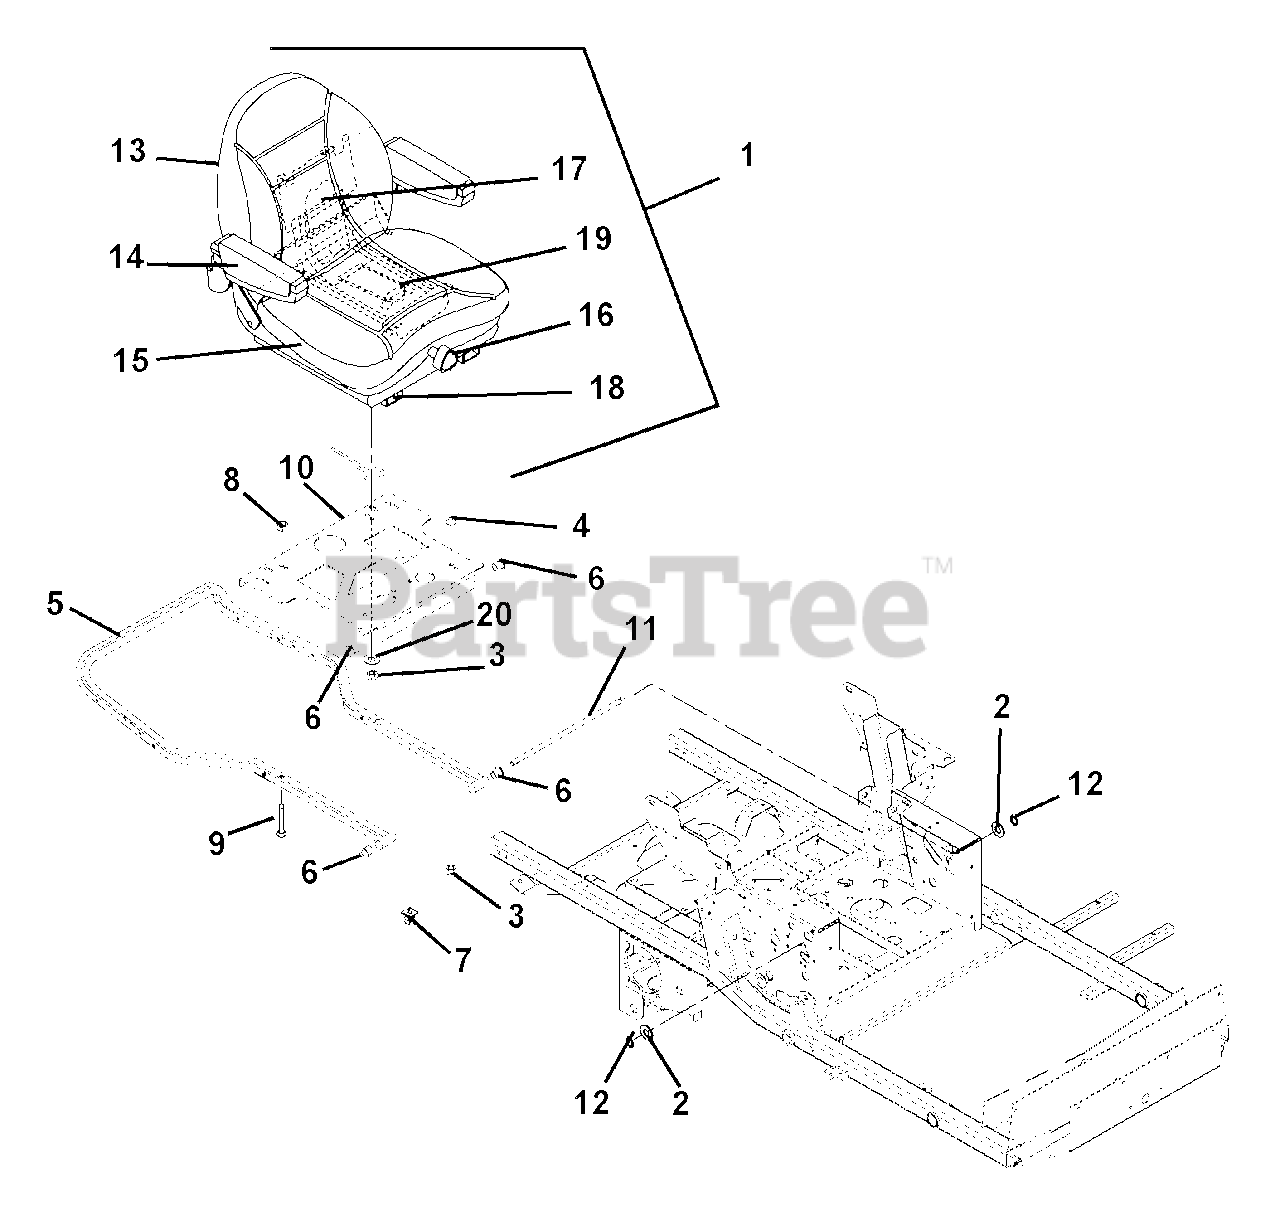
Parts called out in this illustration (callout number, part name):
1	Seat, Suspension
2	Washer, Flat Steel .531 x 1.06 x .095
3	Nut, Locking Top Flange .31-18
4	Bushing, Sleeve .377 x .624 x .235
5	Weldment, Hood Frame
6	Bushing-Flange .515 x .750 x .745 x 1.00
8	Nut, Locking Top Flange .38-16
9	Bolt, Rib Neck .38-16 x 1.50
10	Weldment, Seat Pivot Plate
11	Rod, Seat Frame Pivot
12	Ring, Retaining External .500 x .050
13	Kit, Back Cushion
15	Kit, Seat Cushion
16	Kit, Seat Knobs
17	Kit, Seat Back
18	Kit, Seat Slides
19	Kit, Seat, Spring and Saddle
20	Washer, Flat Steel .328 x 1.00 x .094
